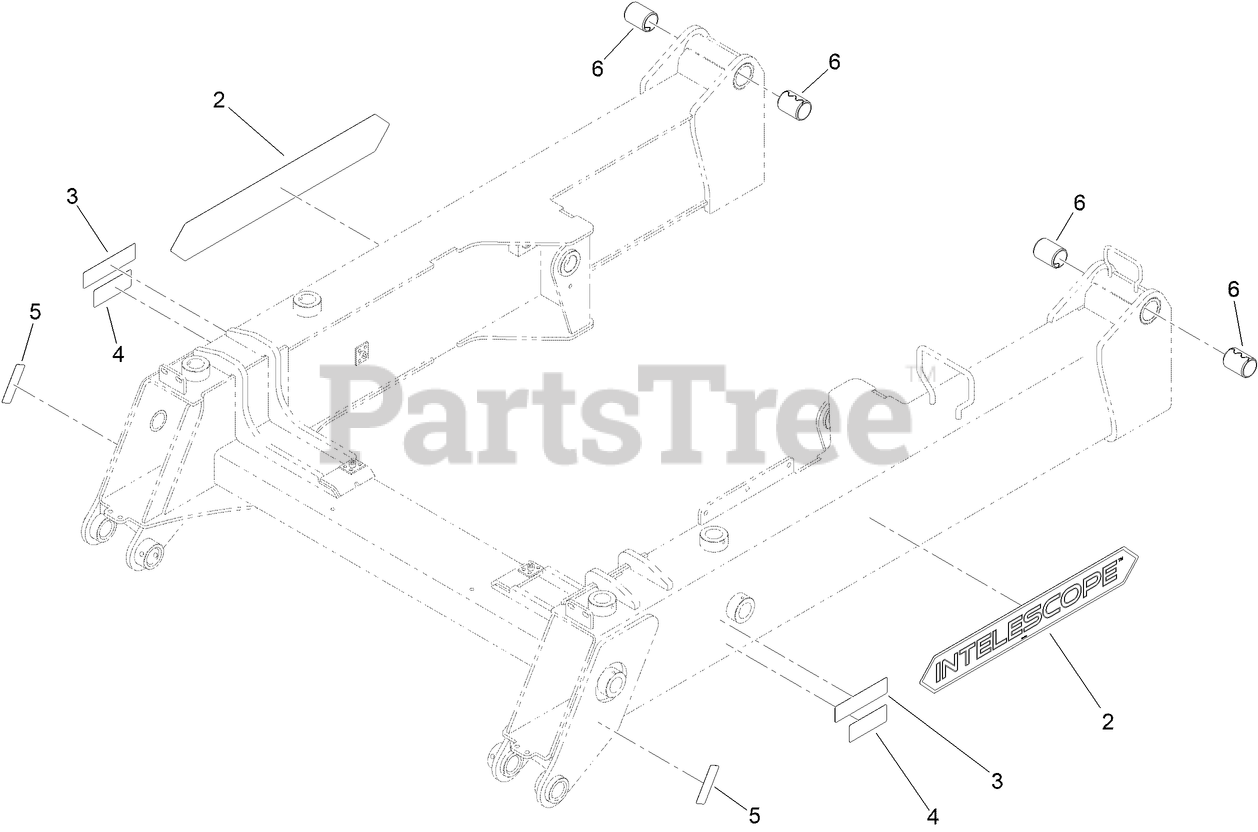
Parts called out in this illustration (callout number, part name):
2	DECAL-INTELESCOPE
3	DECAL-WARNING, CRUSHING
4	DECAL-WARNING, BYSTANDERS
5	DECAL-WARNING, PINCH POINT
6	BUSHING-SPRING
